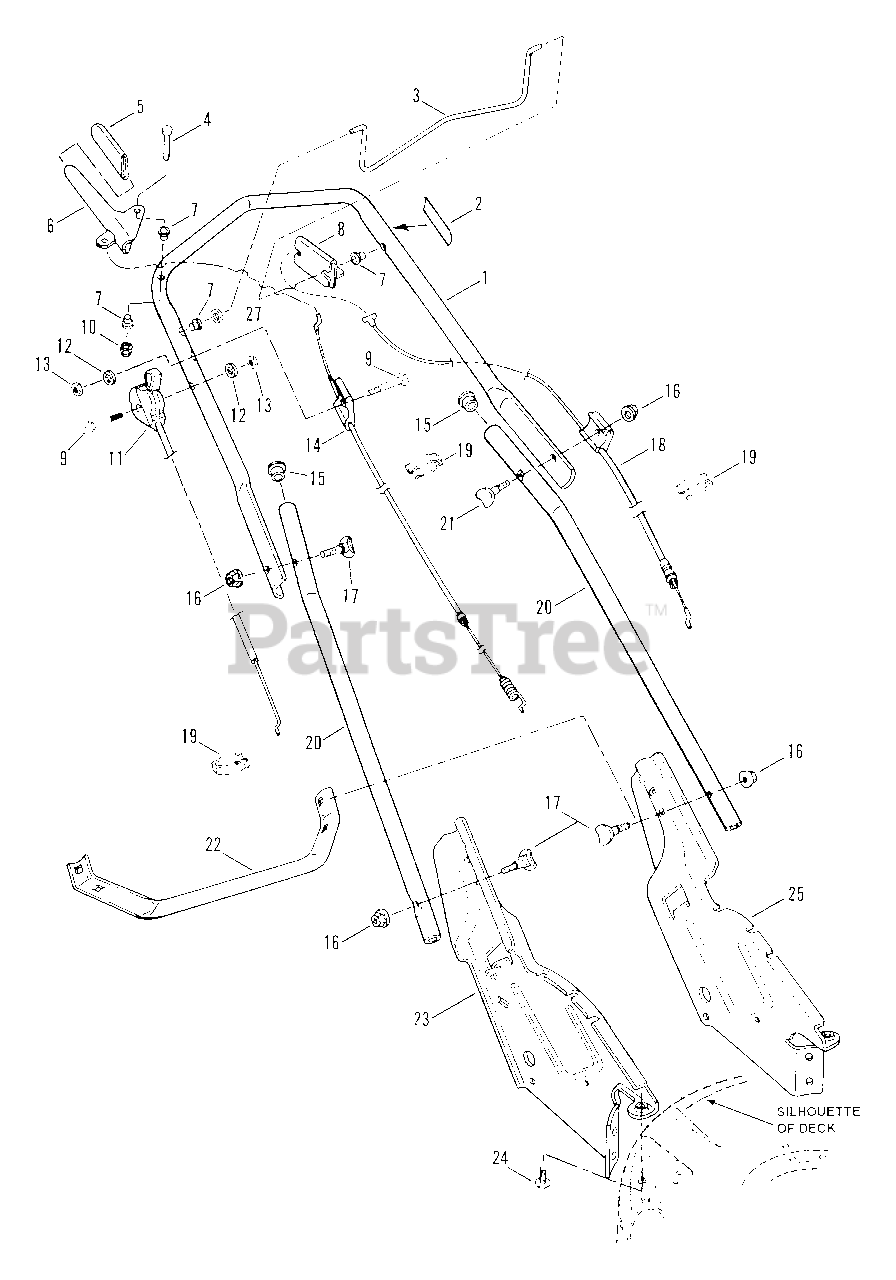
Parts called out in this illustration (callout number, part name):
1	HANDLE, Upper
2	DECAL, Blade Control
3	CONTROL, Blade
4	PIN, .250 Dia. x 1 1/2"
5	GRIP, Wheel Drive
6	HANDLE, Wheel Drive
7	BUSHING
8	CLIP, Blade Control
9	SCREW, 1/4-28 x 2" Hex Head Cap, Grade 5
10	NUT, 1/4 Push
11	CONTROL, Throttle
12	WASHER, 1/4 Internal Tooth Lock
13	NUT, 1/4-28 Hex
14	CABLE, Wheel Drive
15	PLUG
16	NUT, 5/16-18 Hex Flange Lock
17	SCREW, 5/16-18 x 1 1/2" Short Neck Curved Head
18	CABLE, Blade Control
19	CLIP, Wiring Harness
20	HANDLE, Middle
21	SCREW, 5/16-18 x 1 3/4" Short Neck Curved Head
22	BRACE, Handle/Bracket
23	BRACKET, Handle/Wheel (Right Hand)
24	SCREW, 5/16-18 x 1/2" Pan Head, Torx
25	BRACKET, Handle/Wheel (Left Hand)
26	NUT, 5/16-18 Large Flange Lock
27	WASHER, Flat, .125 x .252 I.D. x .625 O.D.
